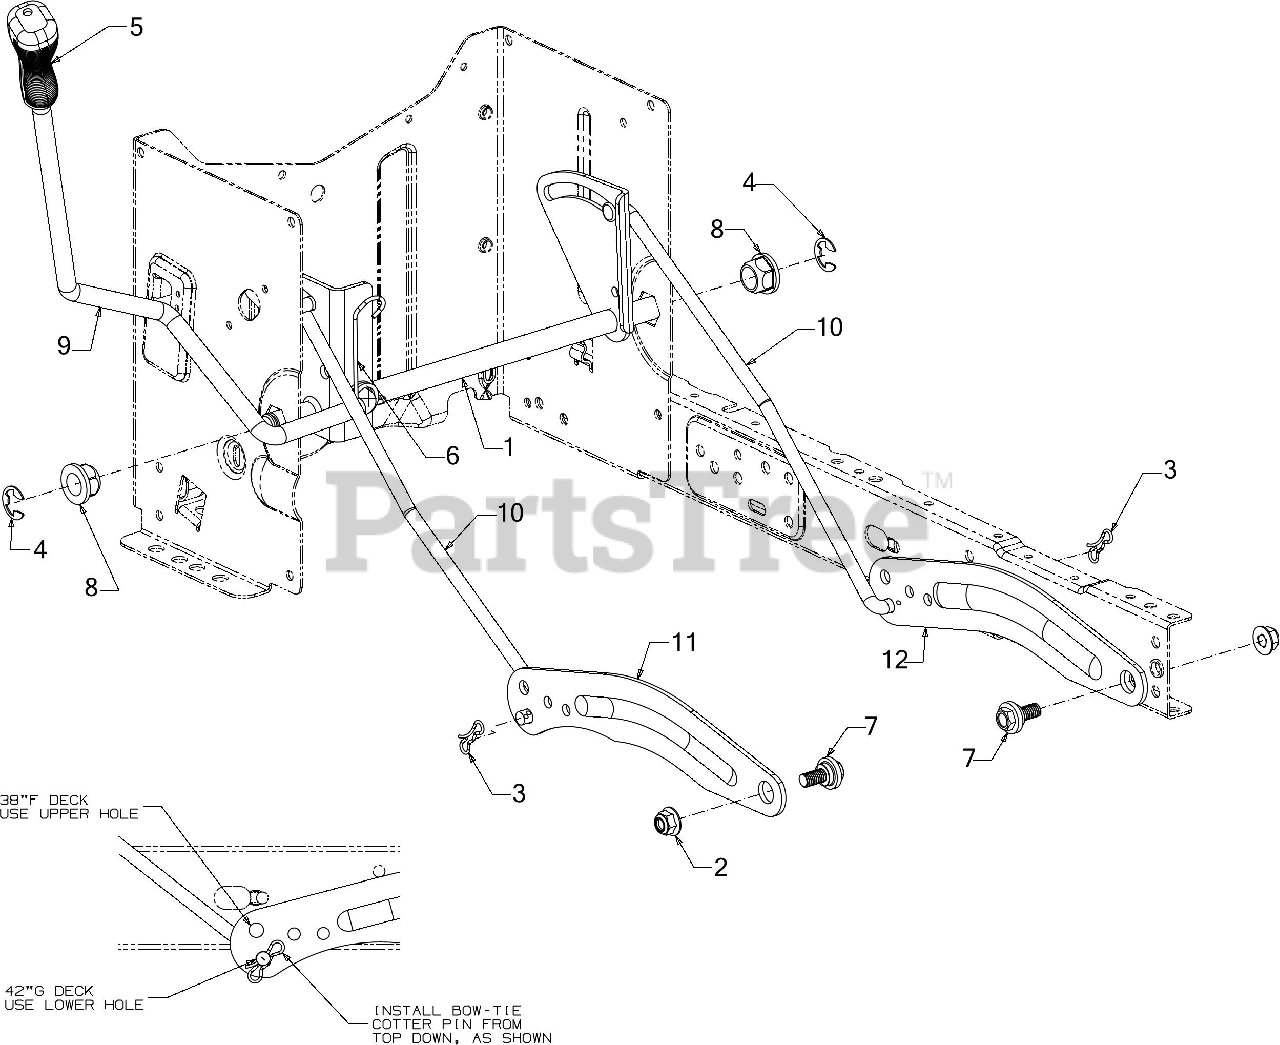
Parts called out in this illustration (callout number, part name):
1	LIFT SHAFT ASSEMBLY
3	BOW TIE COTTER PIN 1/4-5/16
4	E-RING
5	HANDLE GRIP
6	TORSION SPRING
7	SHOULDER SCREW .625X.165X3/8-16
8	FLANGE BEARING
9	DECK LIFT HANDLE
10	LIFT ROD
11	DECK LIFT ARM (RH)
12	DECK LIFT ARM (LH)
